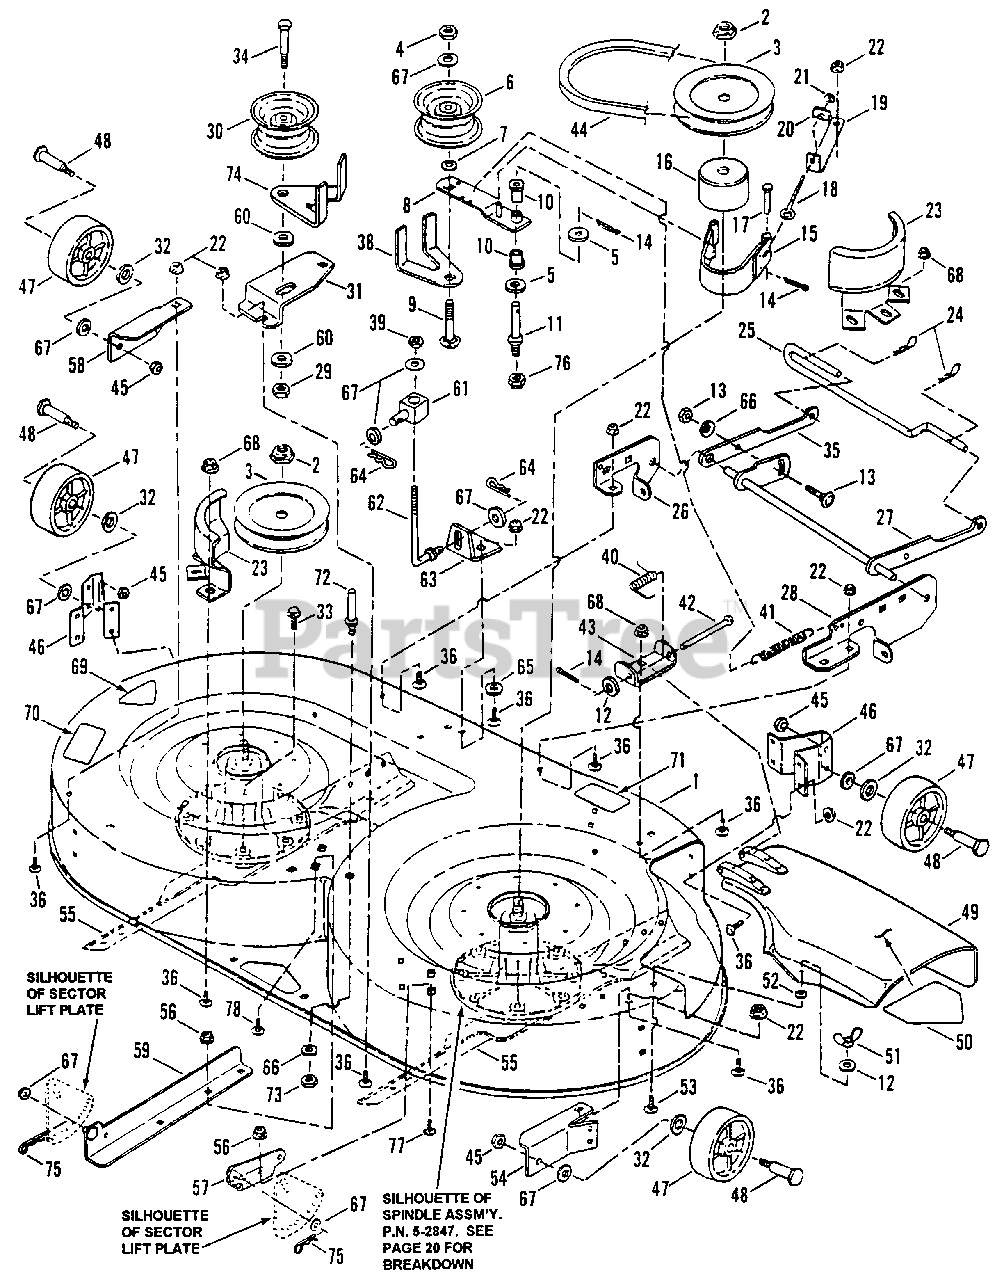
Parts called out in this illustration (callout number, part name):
1	ASSEMBLY, Deck, 38" Cutting
2	NUT, 5/16 Hex Nyloc
3	PULLEY, Spindle
4	NUT, 3/8-16 Hex Nyloc
5	WASHER, 3/8" Flat
6	PULLEY, Idler
7	RETAINER, 3/8 Bolt
8	ARM, Idler Pulley
9	BOLT, 3/8-16 x 2 3/4" Short Neck Carriage, Grade 5
10	BUSHING, Flange
11	STUD, Idler
12	WASHER, Flat
13	BOLT, 3/8-16 x 1 1/4" Short Neck Carriage, Grade 5
14	COTTER-PIN, 3/32 x 3/4"
15	ASSEMBLY, Brake Band
16	DRUM, Brake
17	PIN, 1/4 x 1 5/8" Clevis
18	BOLT, 1/4-20 Eye
19	ANCHOR, Blade Brake
20	NUT, 1/4-20 "T" Lock
21	NUT, 1/4-20 Hex
22	NUT, 5/16-18 Hx. Flng. Lk.
23	GUARD, Belt
24	HAIR-PIN
25	PIN, Deck Hanger
26	BRACKET, Front Lift Arm (Left Side)
27	LIFT, Front Arm
28	BRACKET, Front Lift Arm (Right Side)
29	NUT, 1/2-13 Hex Nyloc
30	PULLEY, Idler
31	BRACKET, Idler
32	WASHER, 1/2 Flat
33	SCREW, 3/8-16 x 3/4" Self-Tapping )
34	BOLT, 1/2-13 x 3 1/2 Hx. Hd. Cap
35	ARM, Front Lift
36	BOLT, 5/16-18 x 5/8 Short Neck Carriage )
38	GUIDE, Belt
39	NUT, 3/8-16 Hex Center Lock
40	SPRING, Chute Deflector Hinge
41	SPRING, Blade Brake
42	PIN, 5/16 x 3 3/16 Clevis
43	HINGE, Chute Deflector
44	BELT, Drive, 38" Cutting Deck, 97.75" EL
45	NUT, 3/8-24 Hex Center Lock
46	BRACKET, Gage Wheel, Front
47	WHEEL, Gage
48	BOLT, 3/8-24 Shoulder
49	ASSEMBLY, Chute Deflector
50	DECAL - DANGER
51	WING-NUT, 5/16-18
52	RETAINER, 5/16 Bolt
53	BOLT, 5/16-18 x 3/4" Short Neck Carriage, Grade 5
54	BRACKET, Wheel (Right Side)
55	BLADE, 19-1/2"
56	NUT, 3/8-16 Hex Flange Lock
57	BRACKET, Rear Deck Lift (Right Side)
58	BRACKET, Wheel (Left Side)
59	BRACKET, Rear Deck Lift (Left Side)
60	WASHER, .406 I.D. x 1.50 O.D. x .20"
61	SWIVEL, Lift
62	BOLT, "J"
63	BRACKET, Angle (Front)
64	HAIR-PIN
65	WASHER, 7/16 Flat
66	WASHER, Cone
67	WASHER, 3/8" Flat
68	NUT, 5/16-18 Hex Lk., Grade 5
69	DECAL, 38"
70	DECAL - CAUTION, Rotating Blades
71	DECAL - CAUTION
72	STOP, Deck 4.5"
73	NUT, 3/8-24 Hex
74	GUIDE, Belt
75	HAIR-PIN, .093 x 1.50"
76	NUT, 5/16-24 Hex Lock
77	BOLT, 3/8-16 x 3/4" Carriage
